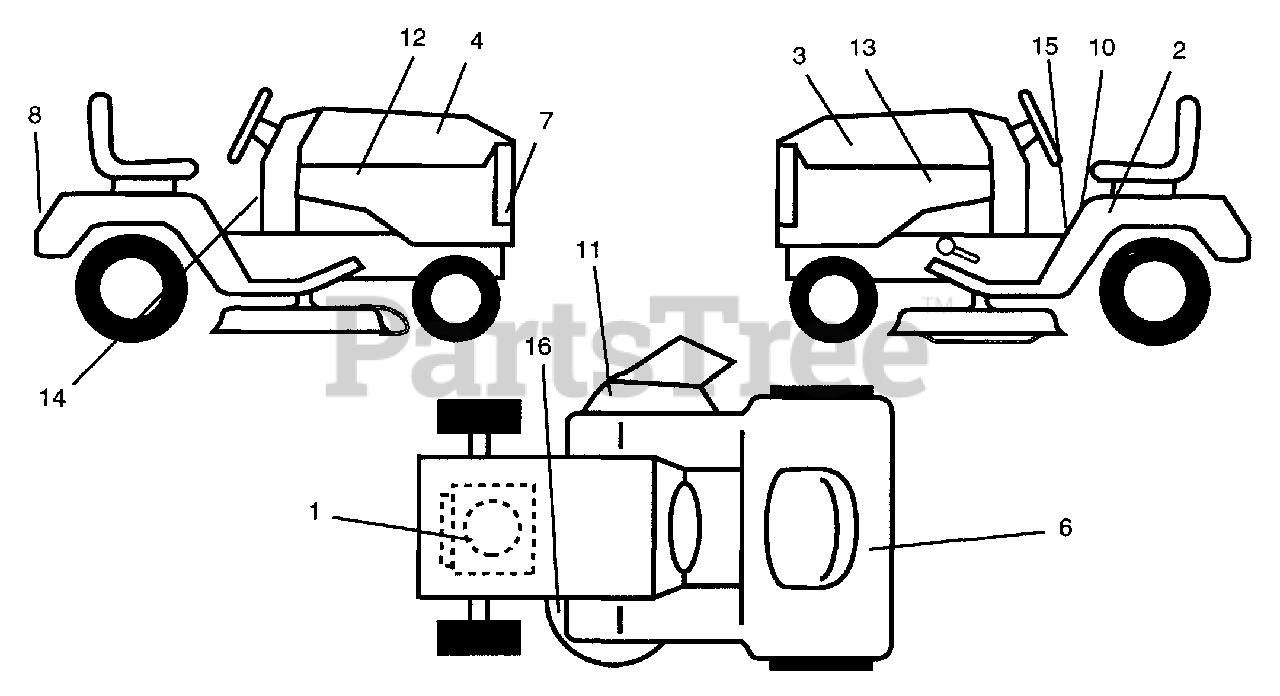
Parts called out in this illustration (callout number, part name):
1	Decal, Engine, HP
2	Decal, Indicator
3	Decal, Hood, L.H.
4	Decal, Hood, R.H.
6	Decal, Caution Battery
7	Decal, Lightbox
8	Decal, Logo, Fender
10	Decal, Fender, Caution
11	Decal, Warning, Multi-Language
12	Decal, Hood, Insert, R.H.
13	Decal, Hood, Insert, L.H.
14	Decal, Europe Stand CE
15	Decal, Instruction, Operating
16	Decal, V-Belt Schematic
CER38	Grass Catcher
